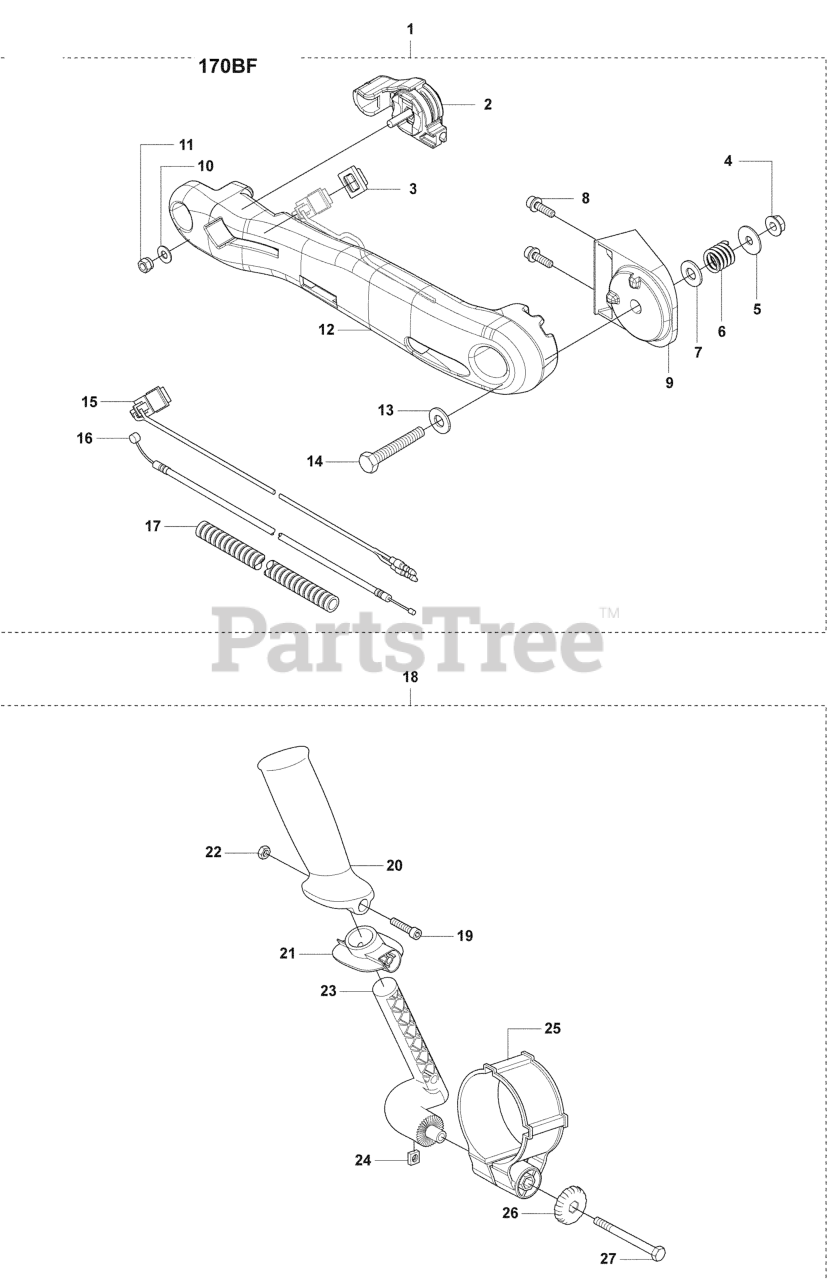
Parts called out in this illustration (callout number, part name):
1	LEVER
2	LEVER
3	CAP
4	NUT
5	WASHER
6	SPRING
7	WASHER
8	SCREW
9	RP_BRACKET
11	NUT
12	ARM
13	WASHER
14	BOLT
16	CABLE COMP
19	SCREW
23	BRACKET
25	HOLDER TH
